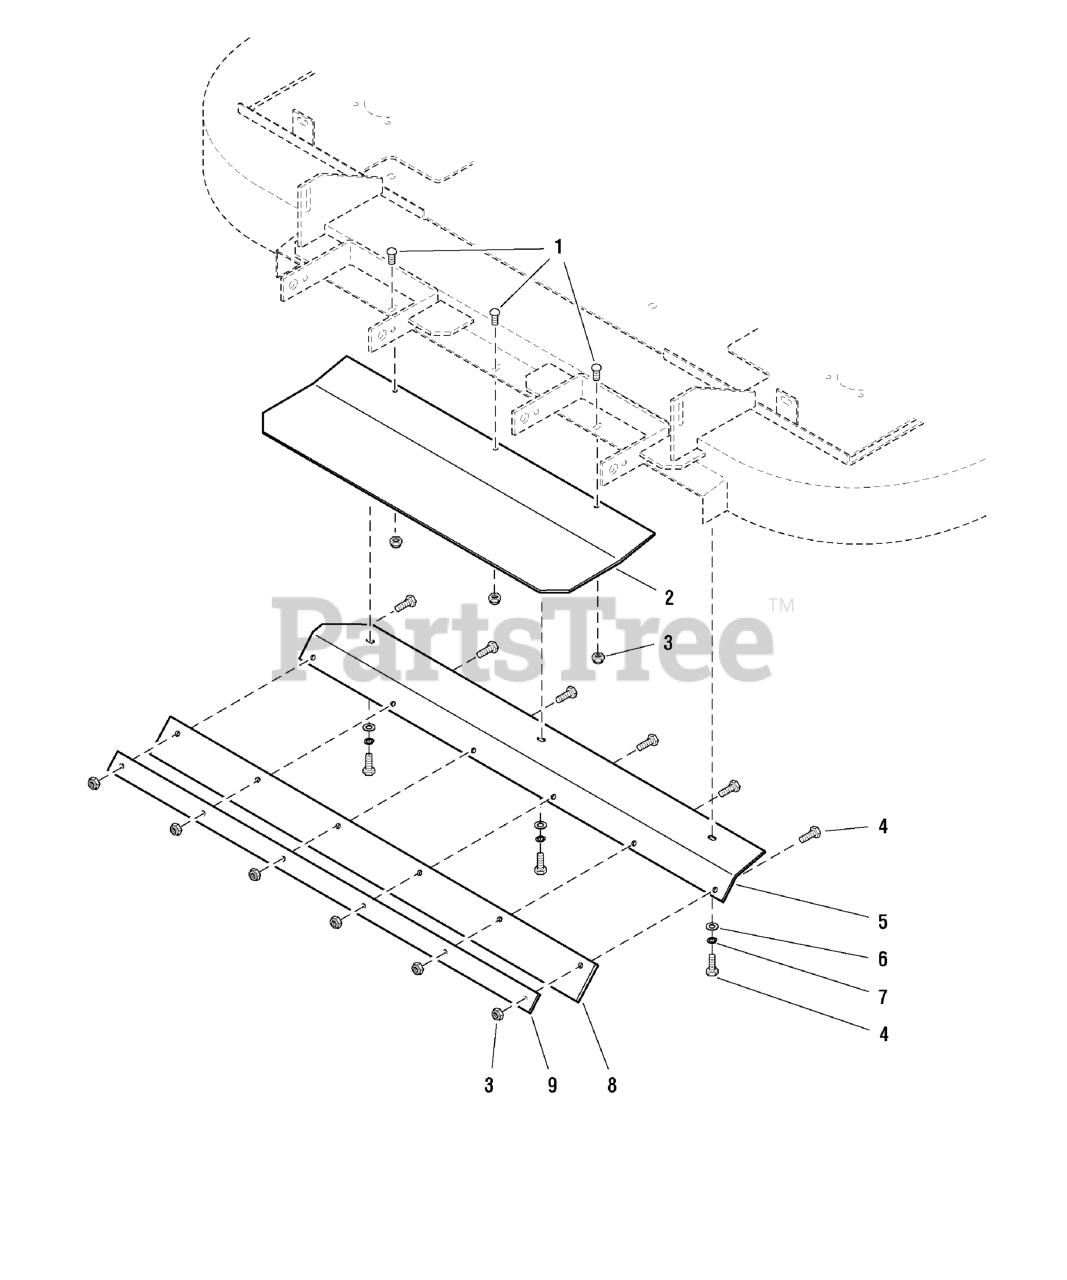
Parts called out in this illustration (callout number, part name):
1	CARRIAGE BOLT, 5/16-18 x 3/4
3	NUT, 5/16-18 Hex Nylon Lock
4	BOLT, 5/16-18 X 1 GD5 YZ
5	DEFLECTOR MOUNT
6	WASHER, 5/16" SAE
7	WASHER, 5/16 LOCK CZ
8	RUBBER DEFLECTOR
9	RETAINING PLATE
